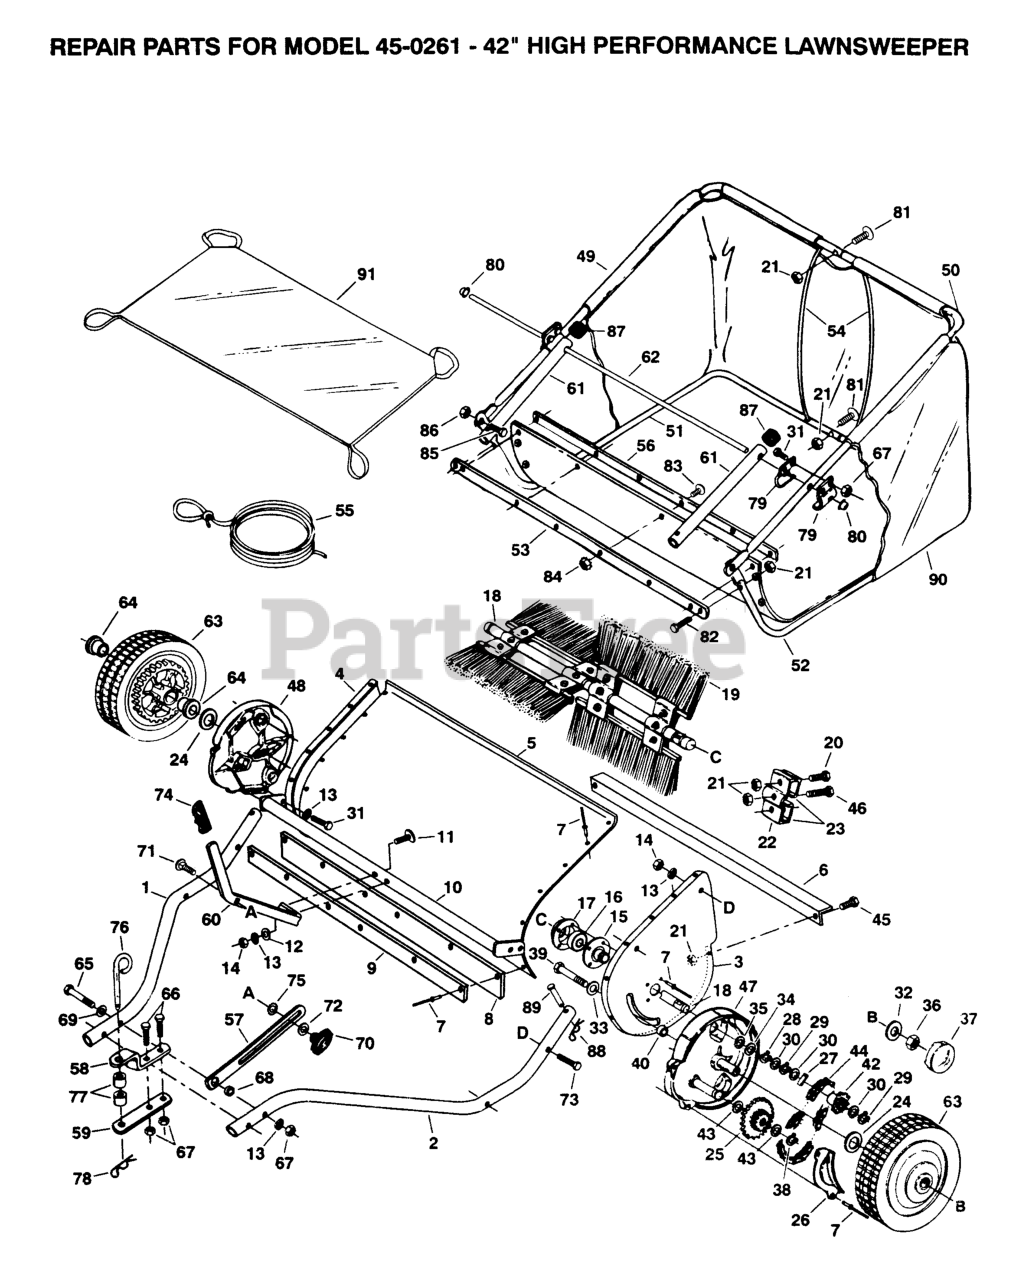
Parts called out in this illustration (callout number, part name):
1	TUBE, R.H.
2	TUBE, L.H.
3	PLATE, L.H.
4	PLATE, R.H.
7	RIVET
11	Bolt, Cv. Hd. 5/16-18 x 1-5/8" Lg.
14	NUT
15	BRUSH BUSHING ASSY
16	BALL BEARING
17	BEARING RETAINER
20	REPL BY 725 23 74-71
22	BRUSHRETAINER DOUBLE
23	BRUSH RETAINER SINGLE
24	Washer, Flat 1-1/8" x .78" x .025"
25	GEAR SPRUCKET SUB ASSY
26	Dust Cover
28	Ring, Retaining 3/4"
29	Retaining Ring .594" I.D.
30	SHIM WASHER
31	BOLT.FIN.HEX.5/16-18X3/4
32	Washer, Flat 1-1/2" x .375" x .062"
33	WASHER
34	FL-WASHER
35	FL WASHER
36	HEX LOCK NUT 3/8-24THD
38	RETAINING RING 1/2Ä
39	HEX BOLT
40	Spacer 13/32" x 5/8" x 3/16"
42	RATCHET SPROCKET
43	Washer, 1/2" x 1" x .02"
44	ROLLERCHAIN 3/8X1/2"
45	Bolt, Hex 1/4-20 x 1/2" Lg.
48	Housing, Wheel Drive Ass'y. R.H.
49	PIPE UP RH
50	PIPE UP LH
51	TUBE LOW RH
52	TUBE LOWER LH
53	STRAP BAG FRAME
54	HOPPER SUPPORT ROD
58	Bracket, Hitch
60	Handle, Height Adjustment
63	WHEEL
64	WHEEL BEARING
65	Bolt, Hex 5/16-18 x 3" Lg.
69	WASHER - M6
70	LOCKNUT M5
71	RP BOLT 5/16-18 X3/4 ZN/YEL GR
72	WASHER BRB 8.4X17
73	SCREW
74	Rubber Grip
75	WASHER, TOOTH LOCK
76	Pin, Hitch
77	Hitch Adjustment Tube
79	HOPPER MOUNTING CLAMPS
81	Curved Head Bolt 1/4-20 x 1"
82	SCREW M6S 6X30
83	Slotted Truss Head Screw #10-32 x 5/8"
84	LOCKNUT M5
85	HEX BOLT
89	PIN CLEVIS 1/4
90	Hopper Bag
